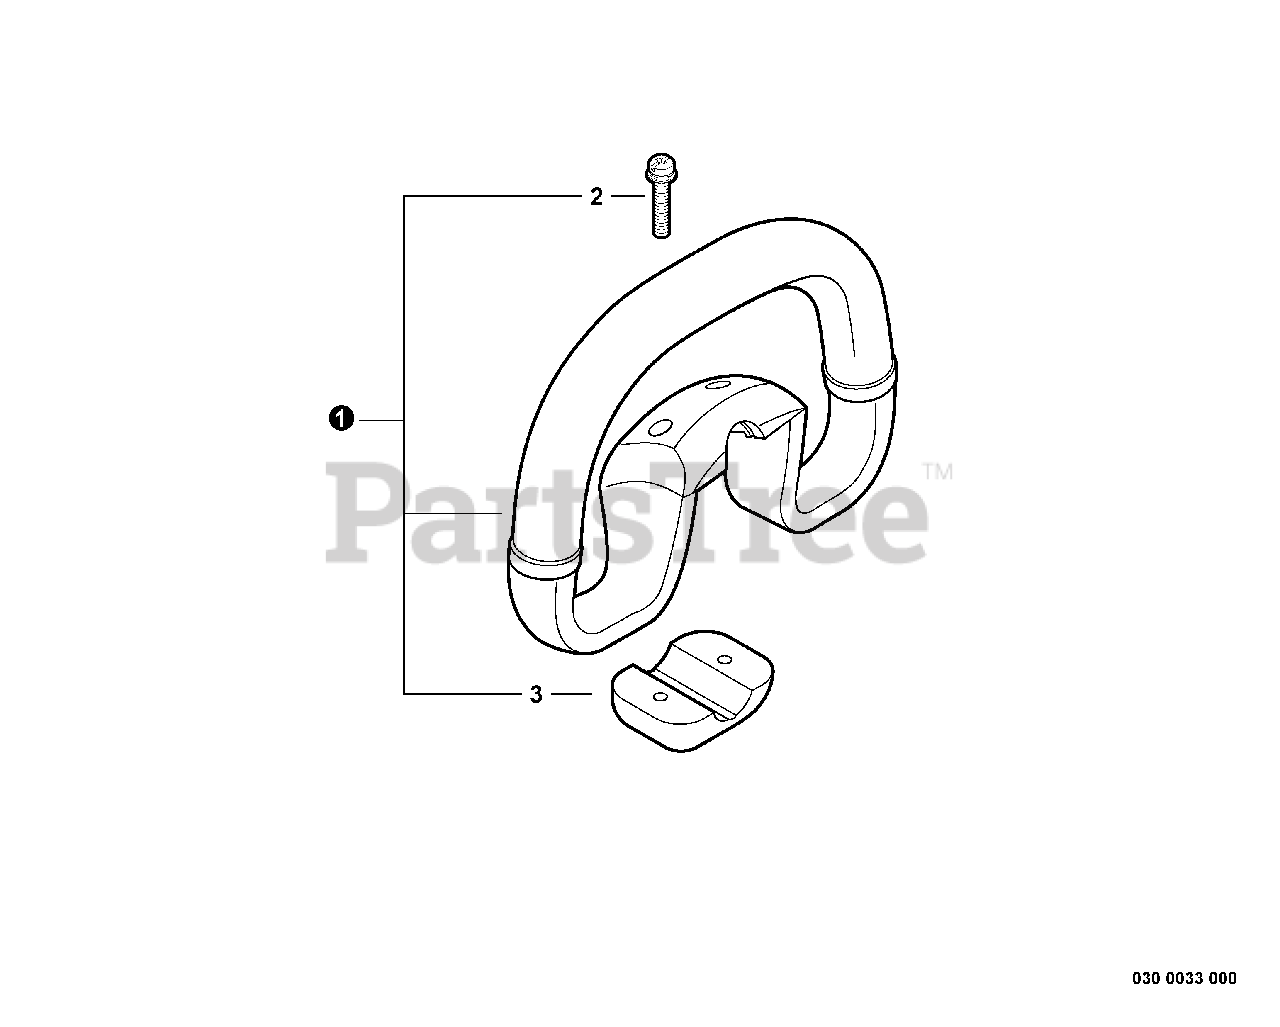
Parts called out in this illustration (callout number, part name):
1	HANDLE ASSY - SUPPORT
2	SCREW 5×40
3	BRACKET, HANDLE
